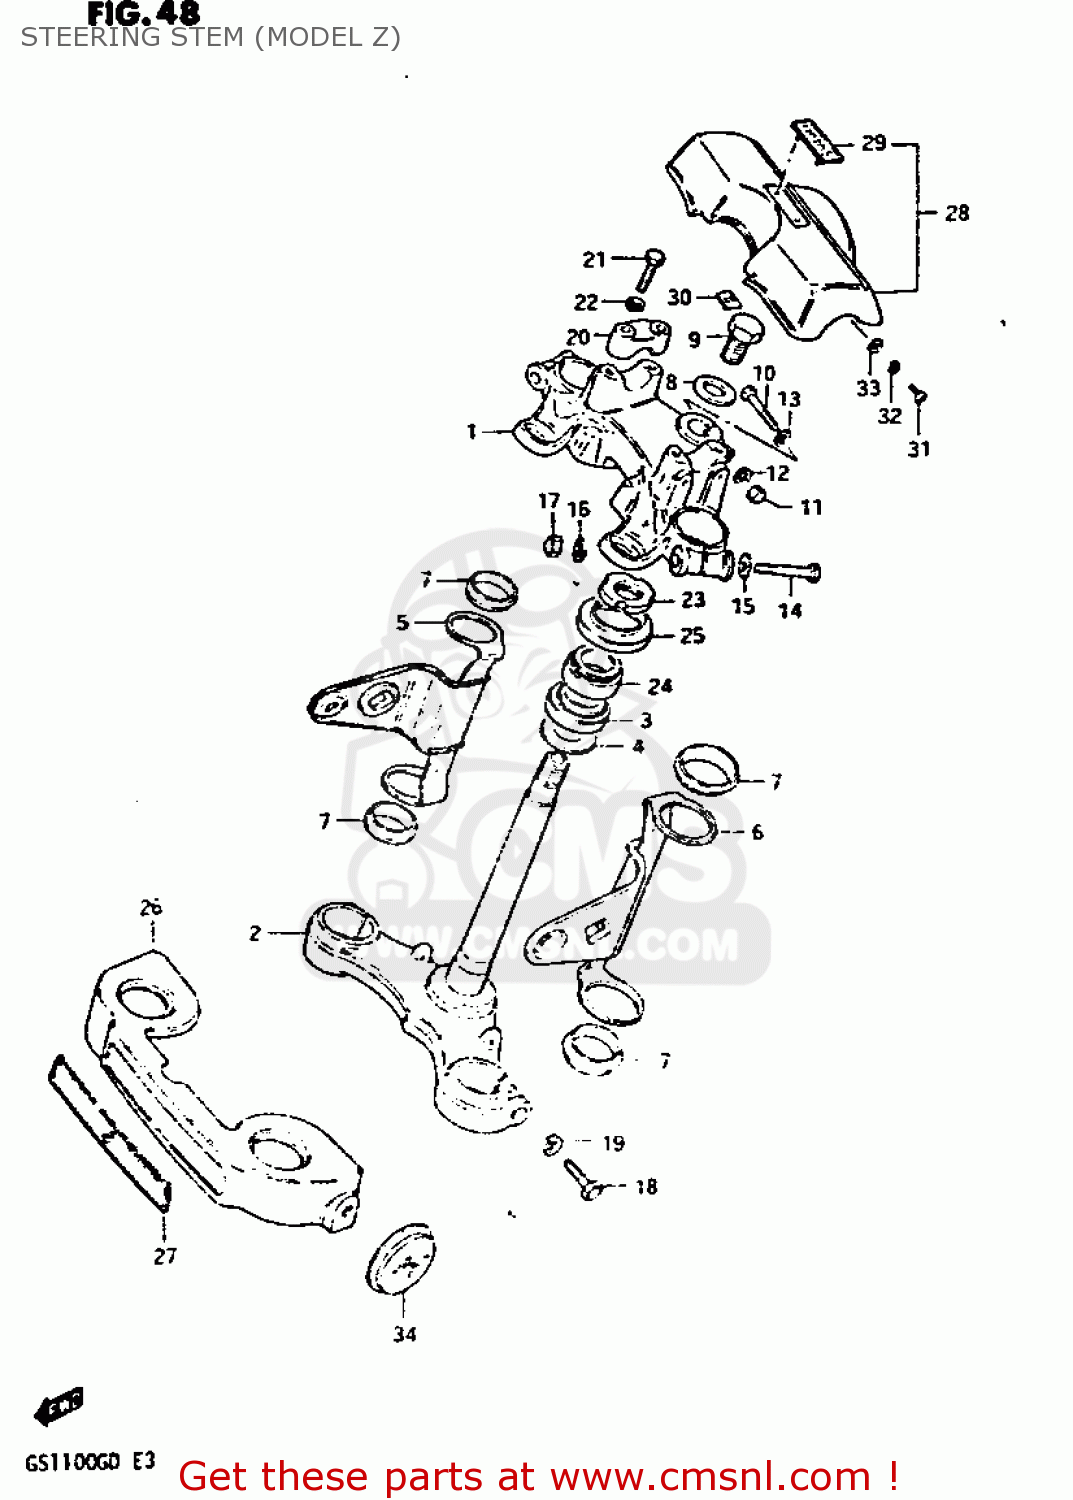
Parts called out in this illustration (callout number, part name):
1	HEAD,STEERING STEM
2	STEM,STEERING
3	BEARING(30X55X17)
4	WASHER,THRUST
5	BRACKET,HEADLAMP,RIGHT
6	BRACKET,HEADLAMP,LEFT
7	CUSHION,HEADLAMP BRACKET
8	WASHER,STEERING STEM
9	NUT,STEM HEAD
10	BOLT 8X50
11	NUT
12	LOCK WASHER
13	WASHER
14	BOLT 10X55
15	WASHER
16	WASHER,LOCK,10
17	NUT
18	BOLT
19	LOCK WASHER
20	HOLDER,HANDLE(BLACK)
21	BOLT
22	LOCK WASHER
23	NUT,STEERING STEM
24	TAPER,ROLLER BEARING
25	DUST SEAL,STEERING UPR
26	COVER,FRONT FORK
27	EMBLEM,FRONT FORK COVER
28	PAD,HANDLEBAR
29	EMBLEM,HANDLE COVER PAD
30	NUT
31	SCREW
32	LOCK WASHER
33	WASHER
34	REFLEX REFLECTOR,RR
